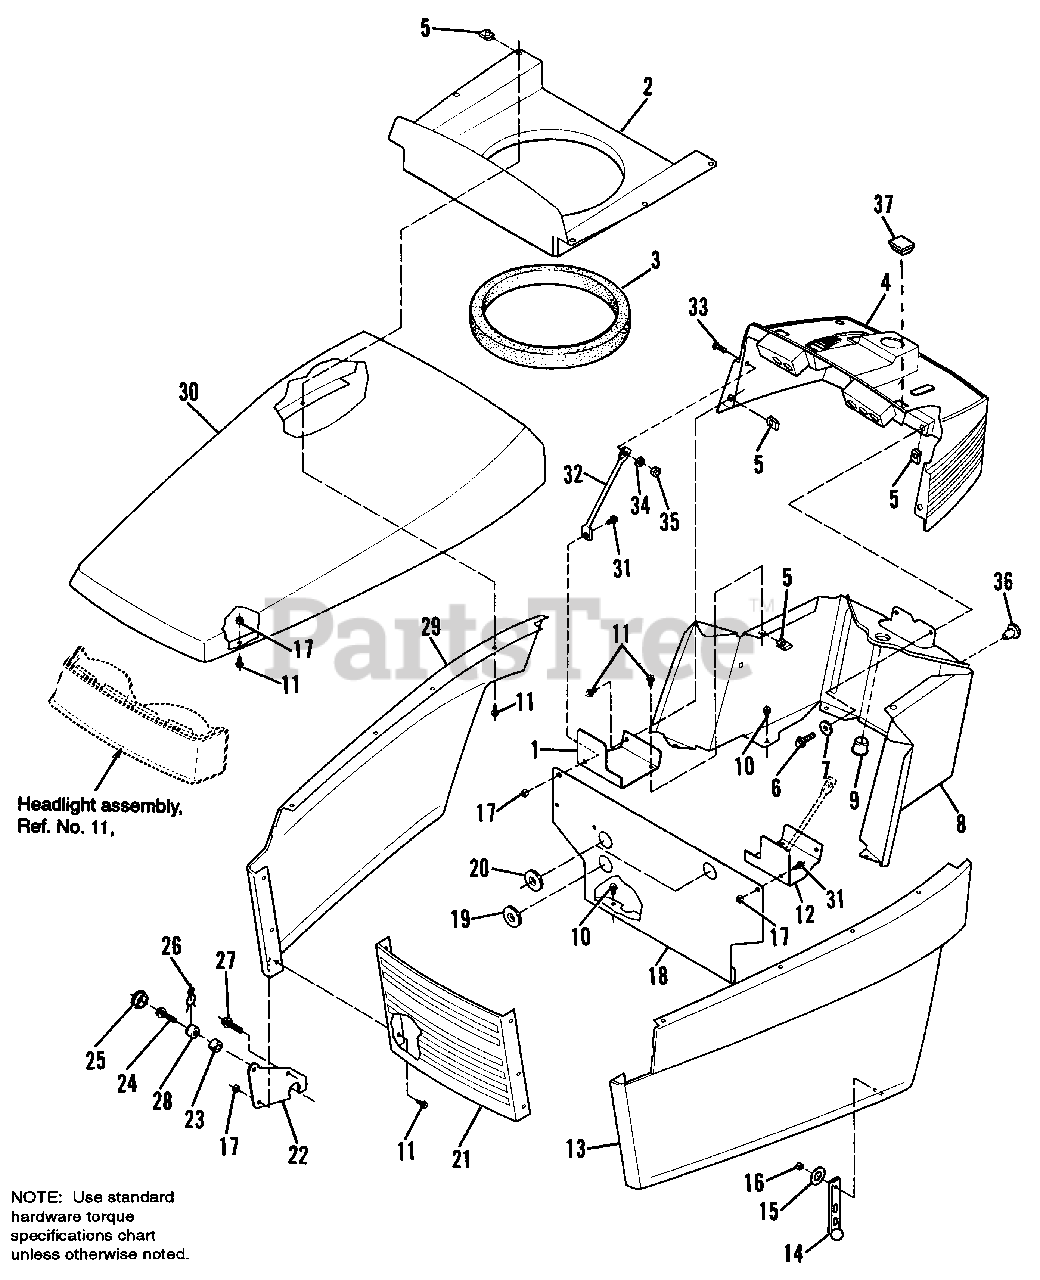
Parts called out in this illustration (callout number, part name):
1	SUPPORT, Bulkhead, R.H.
3	SEAL, Air Duct
4	DASH ASSY. (Gear models)
4	DASH ASSY. (Hydro models)
5	PAL NUT, 1/4-20
6	CAPSCREW, Whizlock, 1/4-20 x 3/4 (Hydro models)
6	CAPSCREW, Whizlock, 1/4-20 x 5/8 (Gear models)
7	WASHER, Plain, 1/4
8	DASH, Lower
9	BUSHING, Nylon
10	SCREW, Taptite, 1/4-20 x 1/2
11	CAPSCREW, Whizlock, 1/4-20 x 5/8 (Qty. 18 on gear models)
12	SUPPORT, Bulkhead, L.H.
13	SIDE PANEL ASSY., L.H. (Orange)
13	SIDE PANEL ASSY., L.H. (Green)
13	SIDE PANEL ASSY., L.H. (Red)
14	STRAP, Hood
15	WASHER, Special
16	NUT, Hex, Lock, Nylon #10-24
17	NUT, Hex, Full Lock, 1/4-20
18	BULKHEAD
19	GROMMET, Wire Harness
20	GROMMETS, Bulkhead (Qty. 1 on hydro models)
21	GRILLE
22	HINGE, Hood
24	SCREW, Taptite, 5/16-18 x 1
25	SPACER, Hood
26	CLIP, Hairpin
27	SCREW, Taptite, 5/16-18 x 5/8
28	PIVOT, Hood
29	SIDE PANEL ASSY., R.H. (Orange)
29	SIDE PANEL ASSY., R.H. (Green)
29	SIDE PANEL ASSY., R.H. (Red)
30	HOOD (Orange)
30	HOOD (Green)
30	HOOD (Reds
31	CAPSCREW, 1/4-20 x 1, Hex Washer Hd.
32	BRACE, Dashboard
33	CARRIAGE BOLT, 1/4-20 x 3/4
34	LOCKWASHER, 1/4
35	NUT, Hex. Full, 1/4-20
36	PLUG, Bumper
37	PLUG, Dash, Electric Lift
